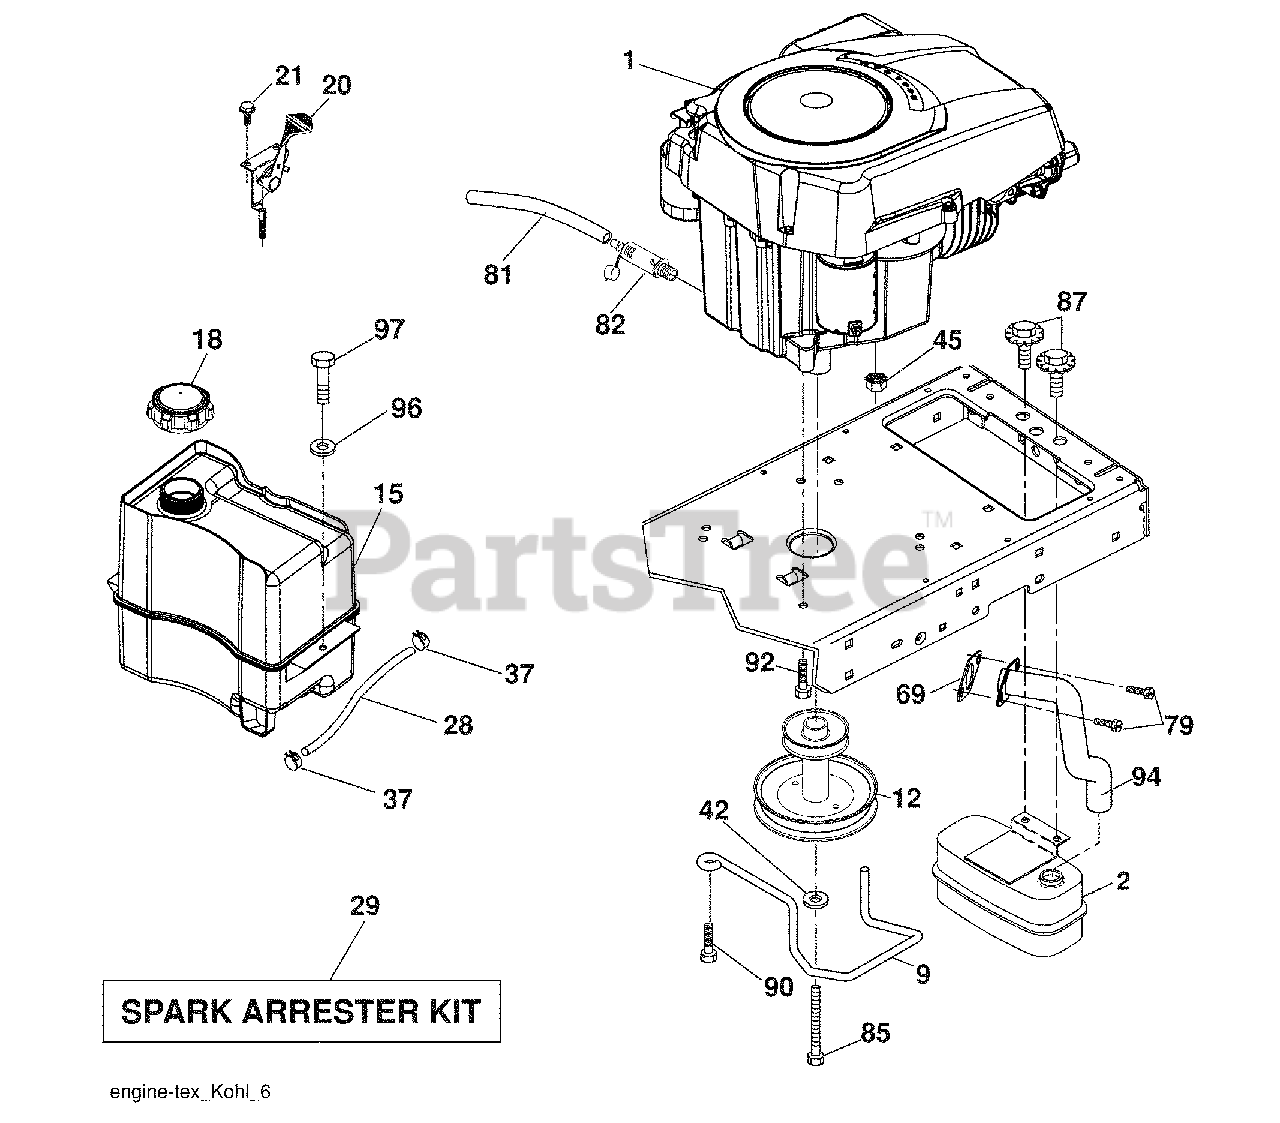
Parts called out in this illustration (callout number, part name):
9	Keeper Belt Engine
12	Pulley Engine
15	Tank Fuel
18	Cap Asm
20	Control Throttle
21	Screw #10 x 0.750
28	Fuel Line
29	Spark Arrester Kit
37	Clamp Hose
42	Washer Lock 7/16
45	Nut Keps Hex 1/4-20 unc
79	Screw Socket Hd. 5/16-18 x .75
81	Tube Drain Oil Easy
82	Plug Drain Oil
85	Bolt Hex 7/16-20 x 4 x Gr. 5-1.5 Thr
87	Bolt 5/16-18 unc x 3/4 w/Sems
90	Screw 3/8-16 x 1
92	Screw 3/8-16 x 1
94	Tube Exhaust
96	Washer 9/32 x 7/8 x 16 Ga.
97	Screw 1/4-20 x 3/4
